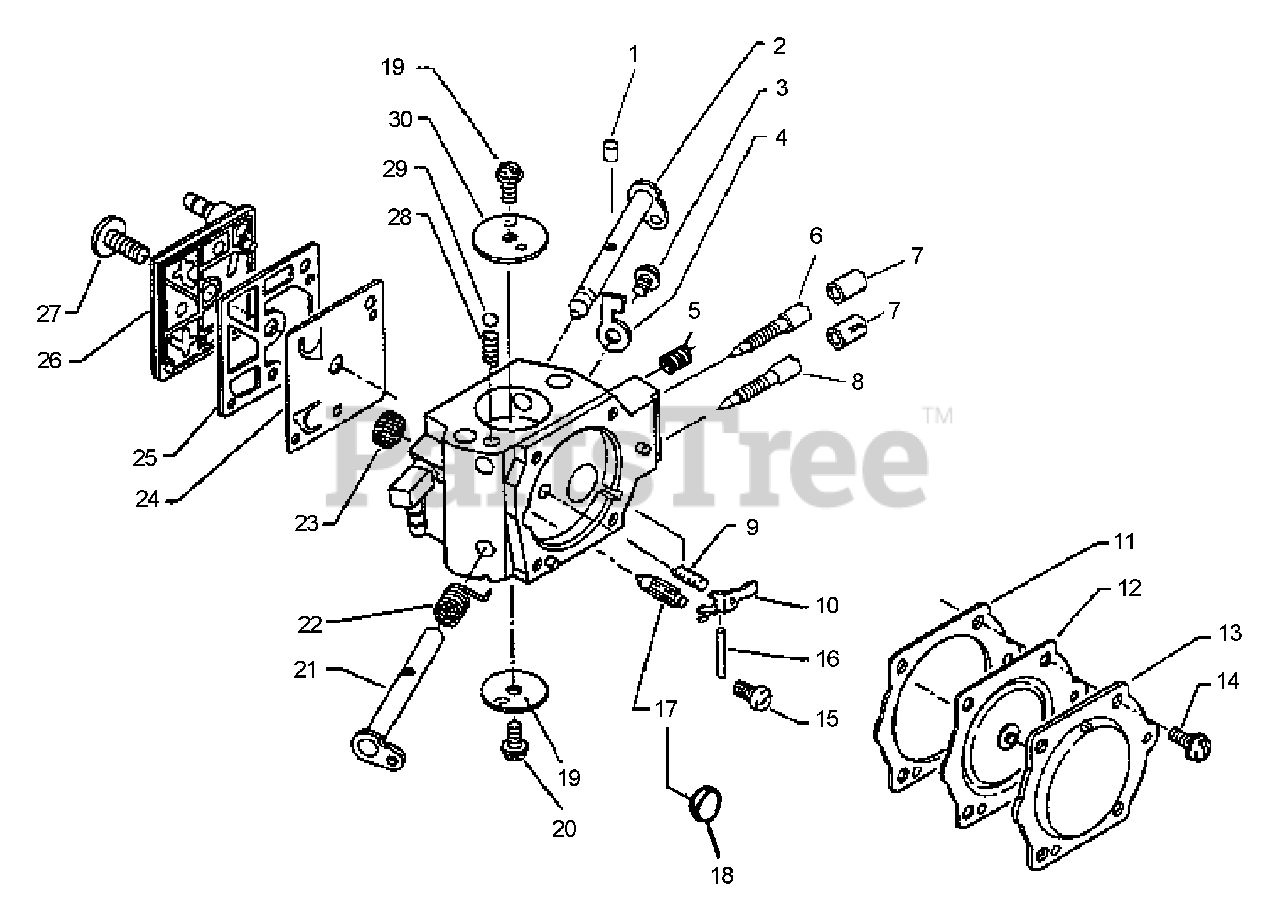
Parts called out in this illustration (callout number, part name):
1	PLUG, FRICTION
2	SHAFT, CHOKE
4	STOP, THROTTLE
5	SPRING, IDLE ADJUST
6	NEEDLE - HIGH SPEED
7	CAP, LIMITER
8	NEEDLE - LOW SPEED
9	SPRING, METERING LEVER
10	LEVER, METERING
11	GASKET, METERING
12	DIAPHRAGM, METERING
13	COVER, METERING
14	SCREW
15	SCREW, METERING LEVER PIN
16	PIN, METERING LEVER
17	VALVE, INLET NEEDLE
18	PLUG, WELCH
19	VALVE, THROTTLE
21	SHAFT, THROTTLE
22	SPRING, THROTTLE RETURN
23	STRAINER
24	DIAPHRAGM, PUMP
25	GASKET, PUMP
26	COVER, PUMP
27	SCREW, PUMP COVER
29	BALL, CHOKE
30	VALVE, CHOKE
